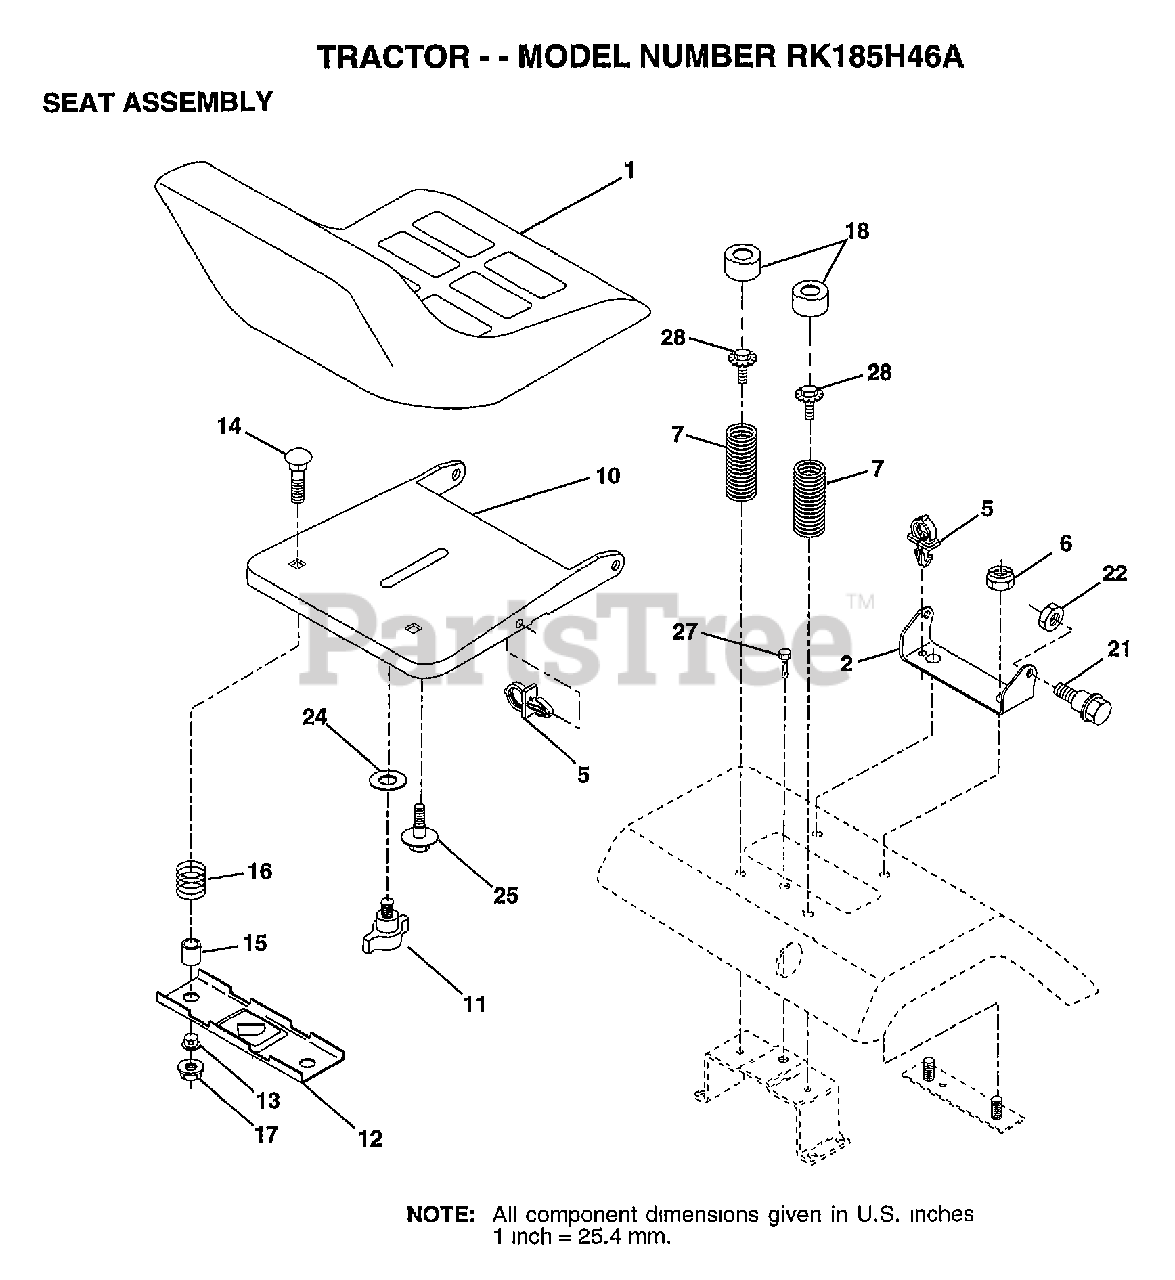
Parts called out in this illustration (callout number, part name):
1	SEAT.2500/1516.BK
2	BRACKET PVT SEAT
5	CLIP.PUSH-IN.HING
6	NUT
7	SPRING COMPRESSIO
10	PAN-SEAT
11	KNOB.SEAT.ADJ.WINGNUT
12	BRKT SWITCH
13	BUSHING
14	BOLT-RD HD SQ NK
15	SPACER SPLIT
16	SPRING COMPRESSED
18	CAP SPRING
21	"BOLT,SHOULDER"
22	NUT
24	WASHER
25	"BOLT,SHOULDER"
27	SCREW LT
28	BOLT.5/16-18.UNC
